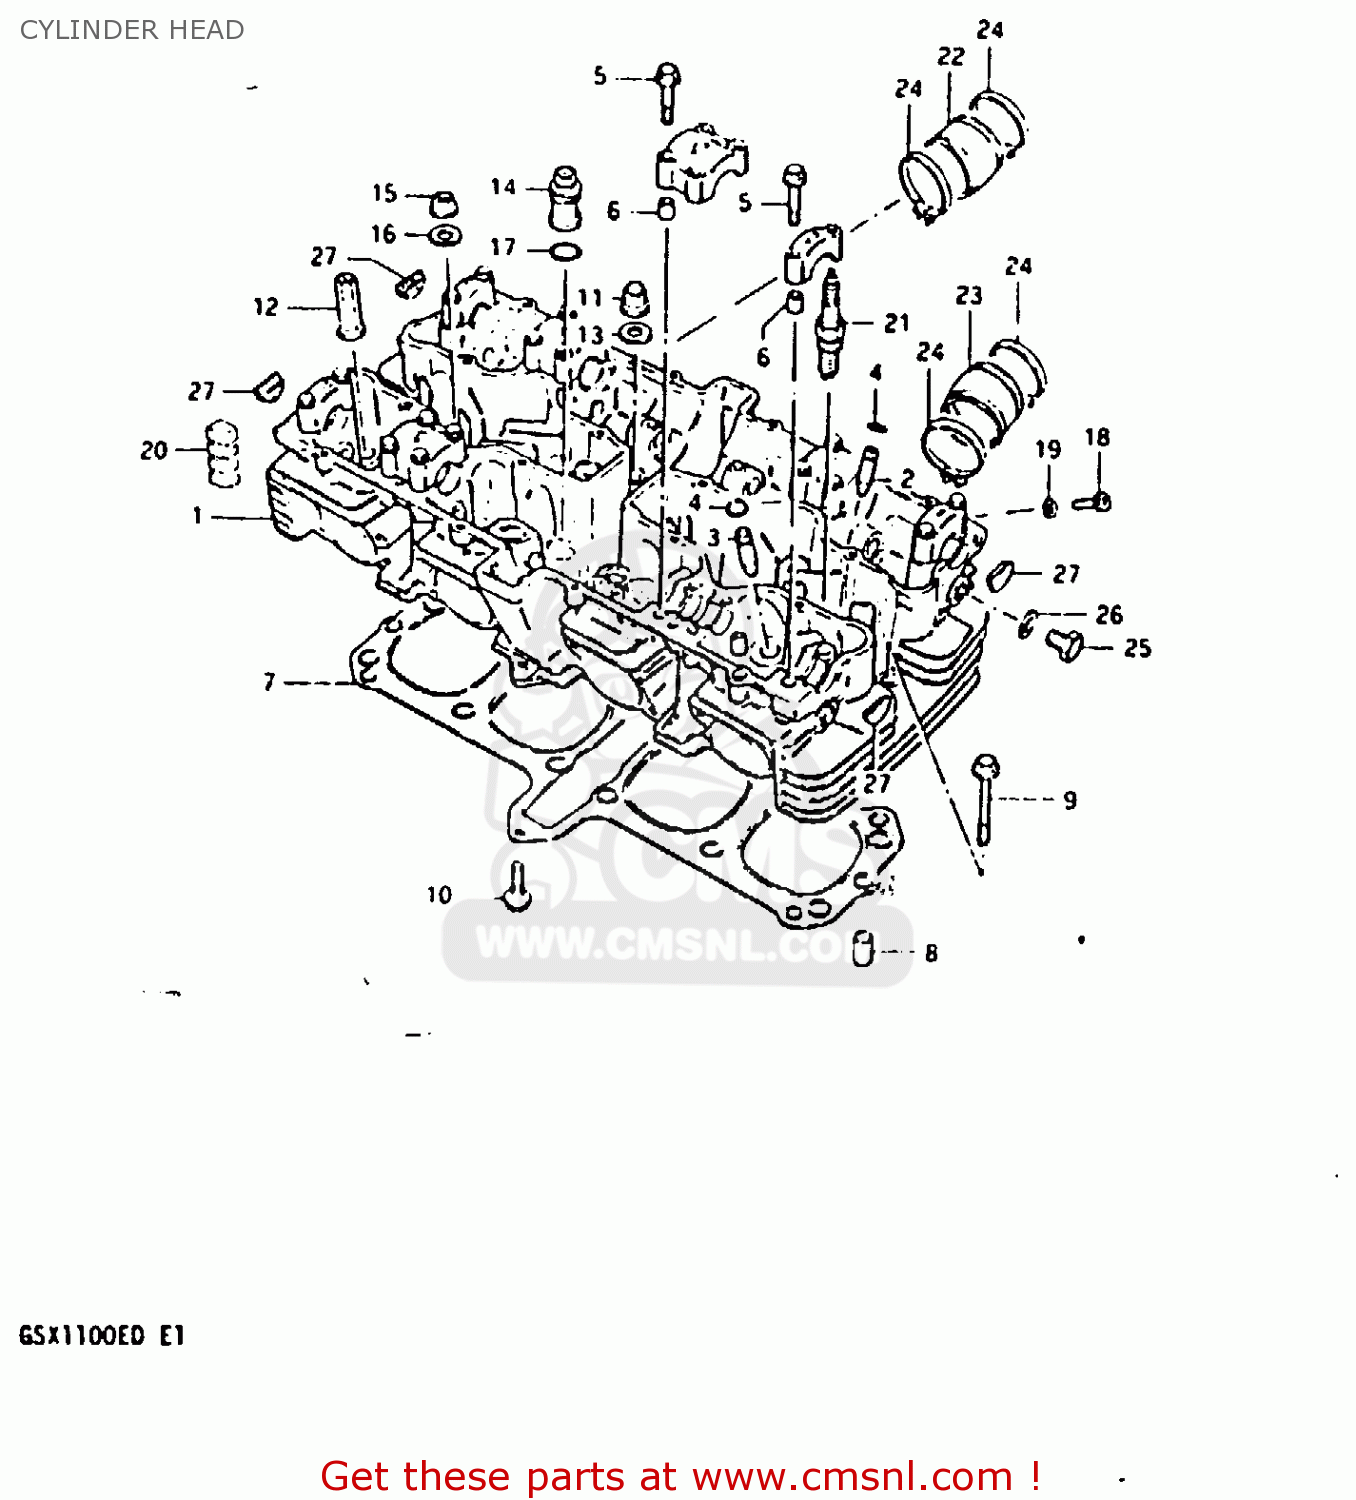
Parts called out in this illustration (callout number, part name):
1	HEAD ASSY,CYLINDER
2	GUIDE,INTAKE VALVE
3	GUIDE,INTAKE VALVE
4	RING,SNAP
5	BOLT(6X39)
6	PIN(6.2X8X11)
7	GASKET,CYLINDER HEAD (NAS)
8	PIN
9	BOLT
10	BOLT
11	NUT
12	NUT
13	GASKET(10.5X22X2) (NAS)
14	NUT,CYLINDER HEAD SEAL
15	NUT
16	WASHER(10.5X22X2.3)
17	O RING(D:2.4,ID:16.8)
18	BOLT
19	GASKET(5.3X9.3X1.2) (NAS)
20	PAD,CYLINDER
21	SPARK PLUG DR8ES-L
22	PIPE,INTAKE,R
23	PIPE,INTAKE,L
24	CLAMP
25	PLUG (14X12)
26	GASKET(14X19.2X2) (NAS)
27	PLUG
